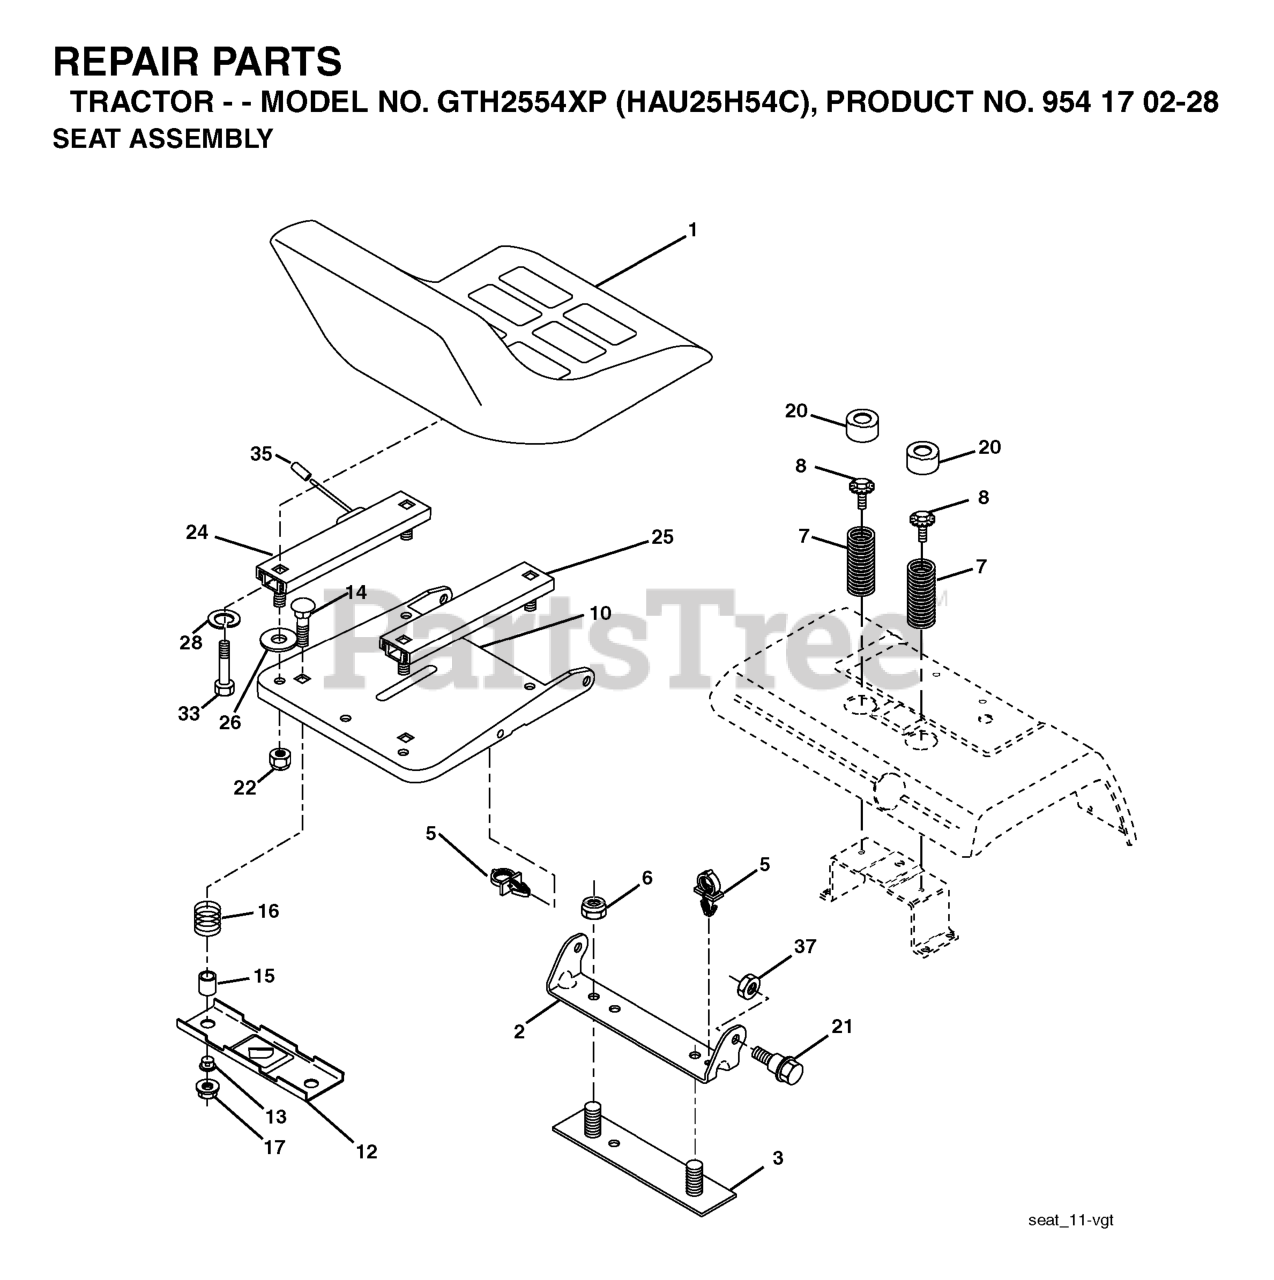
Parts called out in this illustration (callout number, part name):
1	SEAT
2	SEAT PIVOT BRKT
3	STRAP
6	NUT
7	SPRING COMPRESSION
8	BOLT.5/16-18UNCX3/4 W/SEMS.BLK
10	PAN SEAT
12	BRKT SWITCH
14	BOLT.ROUND.HEAD.SQUARE.NECK
15	SPACER SPLIT
16	SPRING COMPRESSED
17	NUT T
20	CAP SPRING
21	BOLT.SHOULDER.5/16-18
22	LOCKNUT
24	TRACK SLIDE, SEAT(L)
25	TRACK SLIDE, SEAT(R)
33	BOLT.FIN.HEX.5/16-18X3/4
35	CAP
37	NUT.71038.31-18.HEX.NYLOCK
